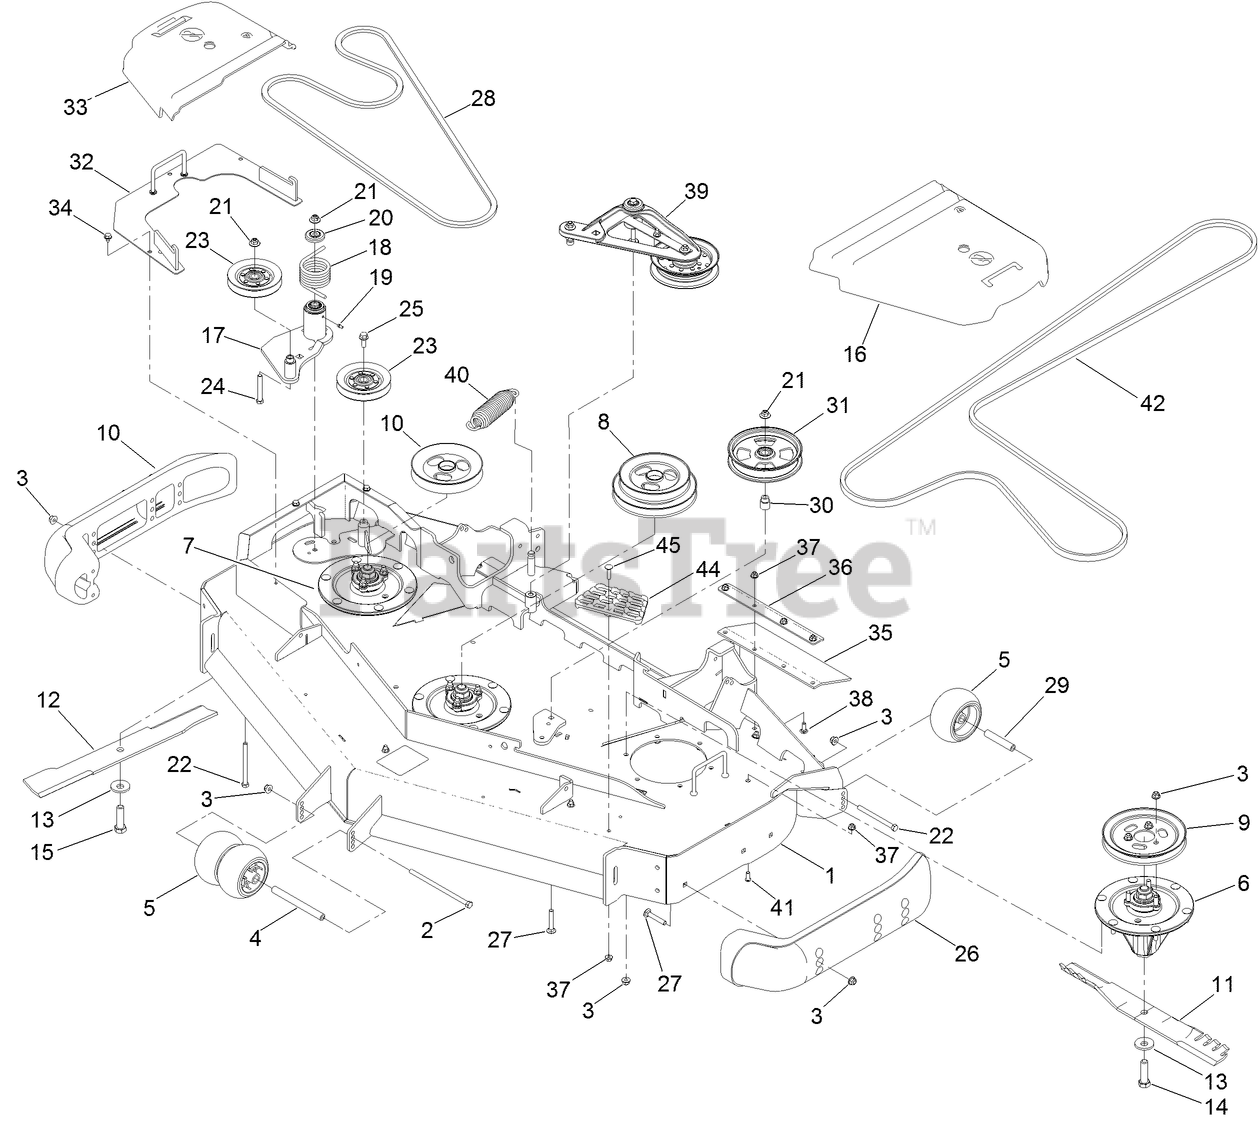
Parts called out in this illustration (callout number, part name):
1	DECK DECAL ASM
2	SCREW-HH
3	NUT-HF, NI
4	SPACER-WHEEL
5	ROLLER-SCALP, ANTI
6	SPINDLE ASM
7	LH SPINDLE ASM
8	PULLEY
9	PULLEY
10	PULLEY
11	BLADE-ATOMIC, 20.5IN
12	BLADE-ROTARY, 20.5IN LOW FLOW
13	WASHER-BLADE BOLT, HEAVY
14	SCREW-BLADE
15	SCREW-BLADE, LH
16	COVER-BELT, LH
17	IDLER ASM
18	SPRING-TORSION
19	FITTING-GREASE
20	GUARD-TOP
21	NUT-FLANGE, NI
22	SCREW-HH
23	SHEAVE
24	SCREW-HH
25	SCREW-HHF
26	SKID-BUMPER, DECK
27	SCREW-HH
29	TUBE-SPANNER
30	BUSHING-IDLER
31	PULLEY-IDLER, FLAT
32	COVER-DRIVE REVERSE
33	COVER-BELT, RH
34	SCREW
35	GUARD-TIRE
36	SUPPORT-OUTER FLAP
37	NUT-HF, NI
38	SCREW-CARR
39	DECK IDLER ASM
40	SPRING-EXTENSION
41	SCREW-HSBH
44	STEP-DECK
45	SCREW-CARR
